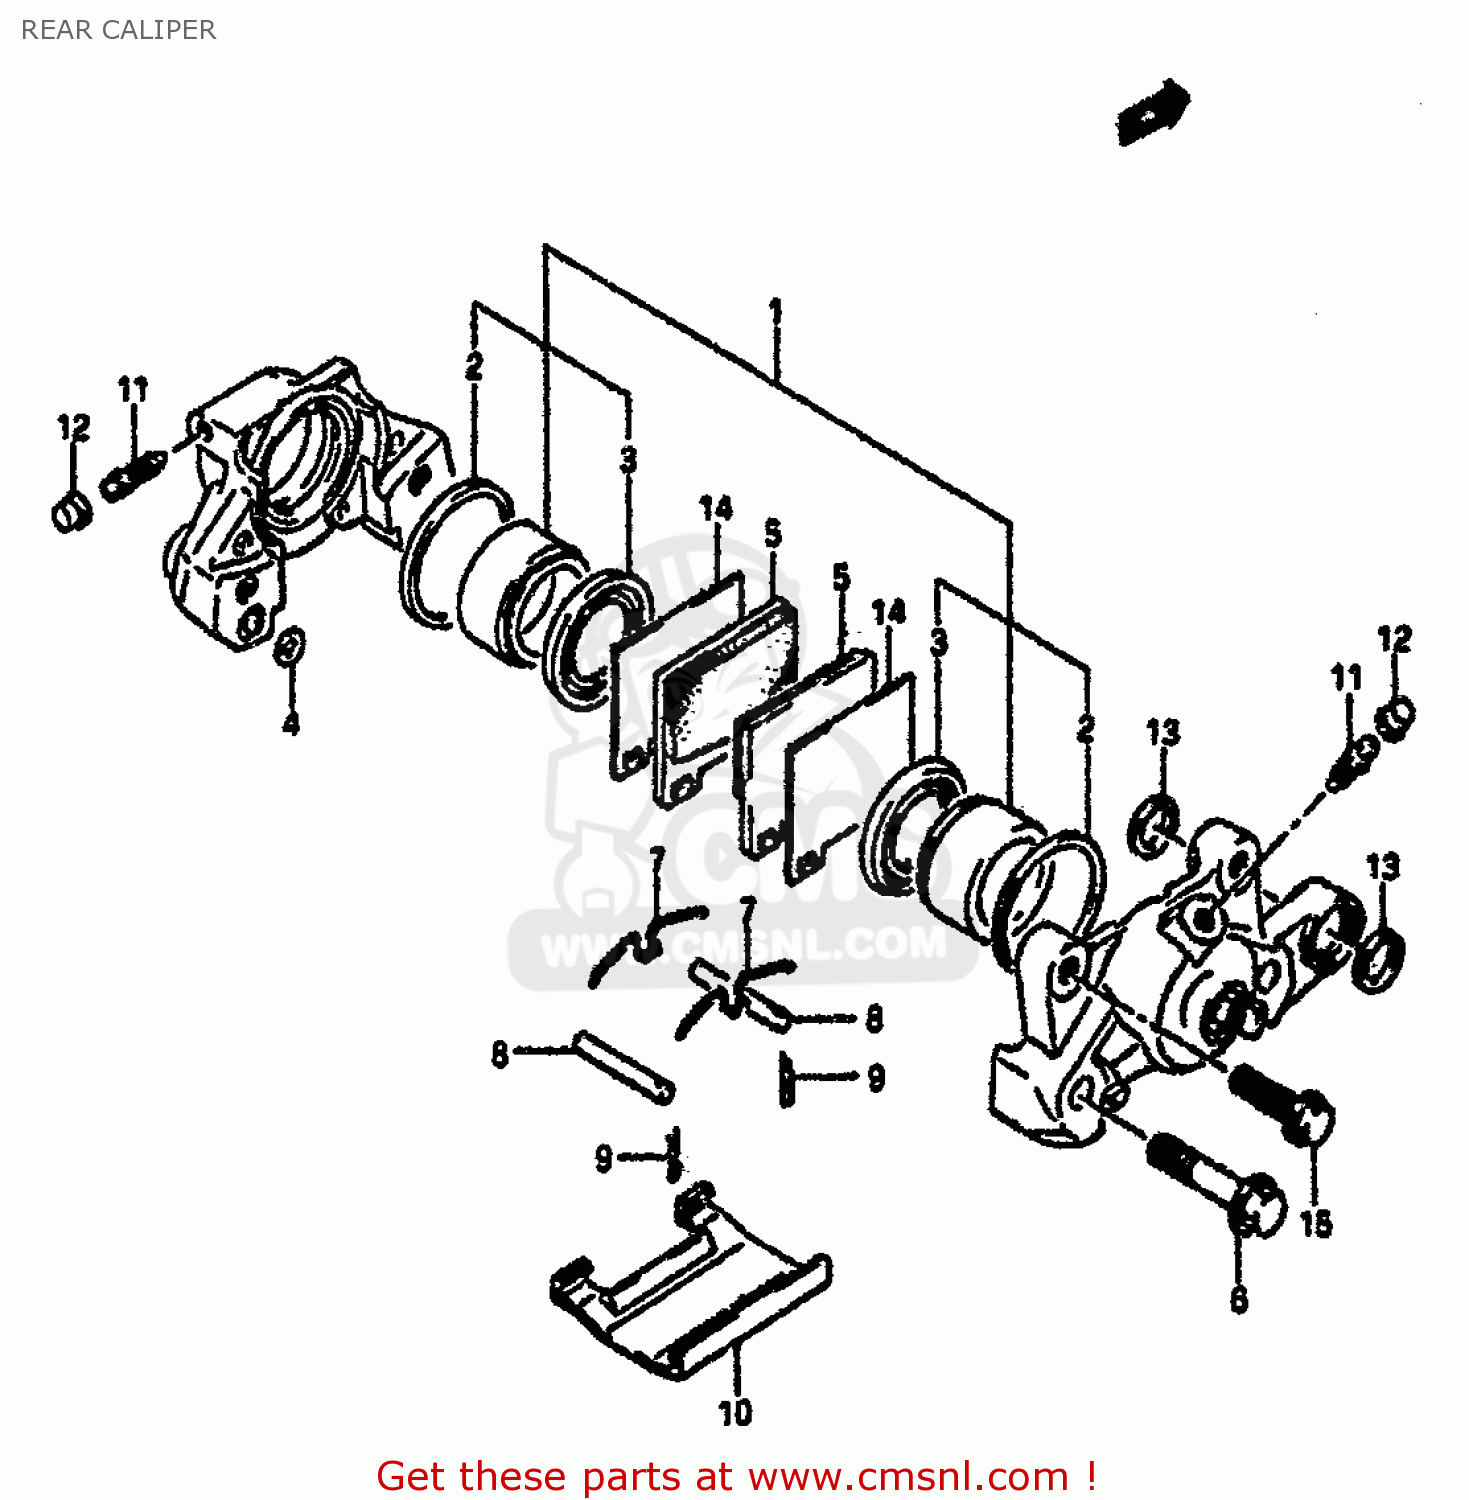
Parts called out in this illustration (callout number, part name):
1	PISTON SET
2	SEAL,PISTON
3	BOOT
4	SEAL,JOINT
5	PAD,BRAKE
6	BOLT
7	SPRING
8	PIN,PAD
9	CLIP,PAD PIN
10	COVER
11	BLEEDER
12	CAP,BREATHER
13	SEAL,RR CUSHION ROD LWR
14	SHIM,PAD
15	BOLT
